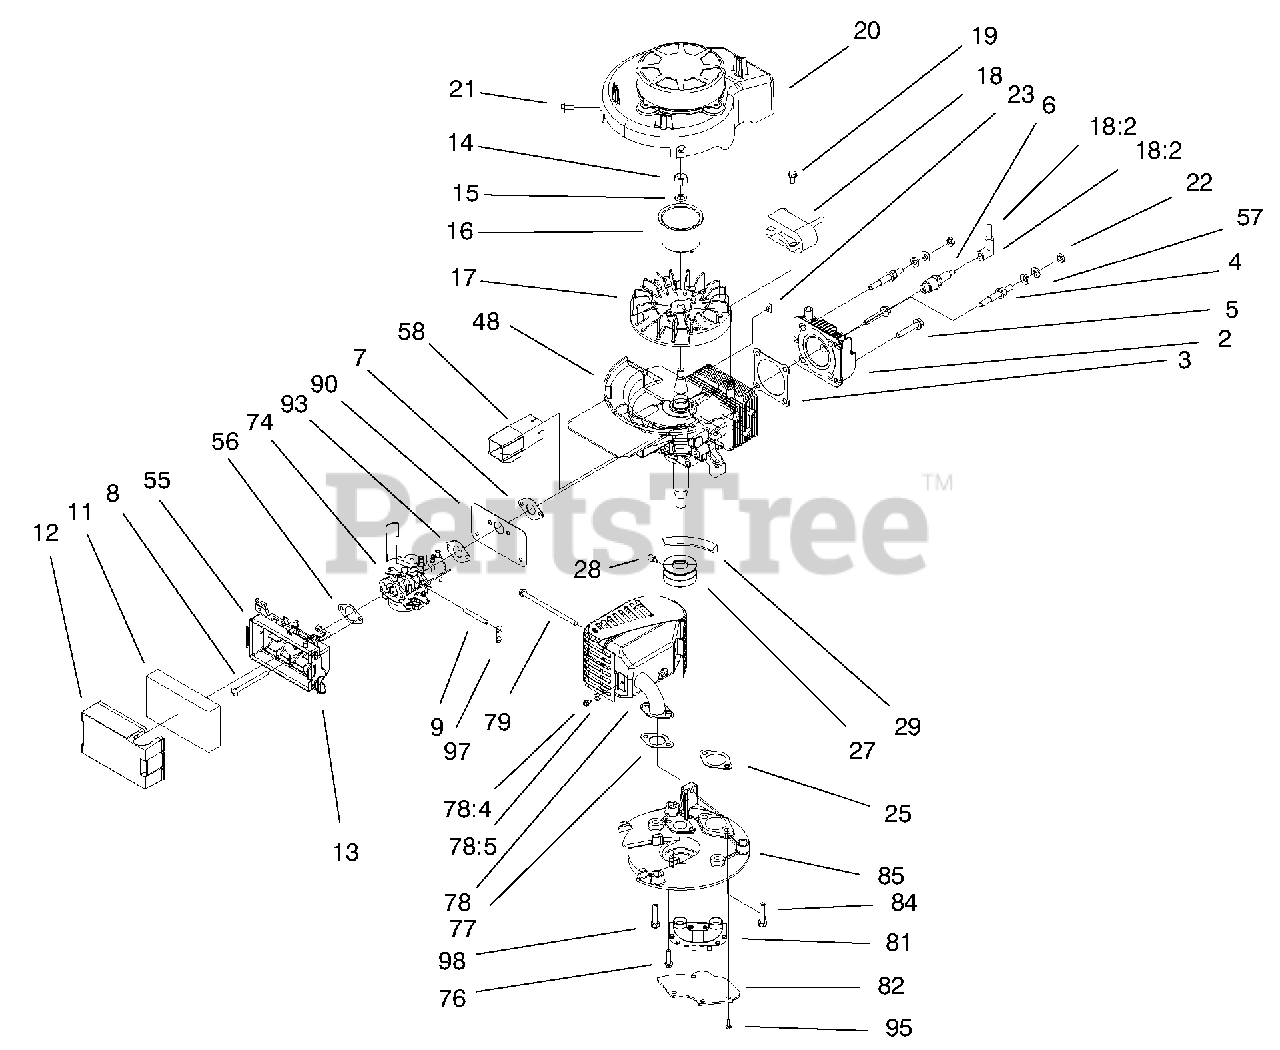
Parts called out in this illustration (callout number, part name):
3	Gasket-Head
6	Spark Plug
7	Intake Gasket
9	Primer Hose
11	Element-Air Filter
12	Cover-Air Filter
13	Retainer-Filter
15	Washer-Lock
16	Cup-Starter
17	Flywheel Machined Recoil
18	Ignition ASM
18:2	High Tension Lead & Cover
18:2	Cover & Terminal
19	Screw-HWH
20	Shroud & Recoil ASM
21	Screw
22	Nut-Lock
25	Gasket-Exhaust
27	Pulley Engine
28	Screw-Set
42	Wire Lead
48	Short Block ASM Service
55	Air Filter Base ASM
56	Gasket-Filter Base
57	Washer-Lock
68	Sealer-Loctite
74	Carburetor ASM
76	Screw-HWH
78	Muffler & Guard
78:5	Lockwasher
81	Transfer Tube
82	Cover Plate
84	Screw-HH
85	Muffler Plate Machining
90	Heat Shield
93	Retainer Wire
97	Retainer Hose
98	Screw-Hhd Washer
